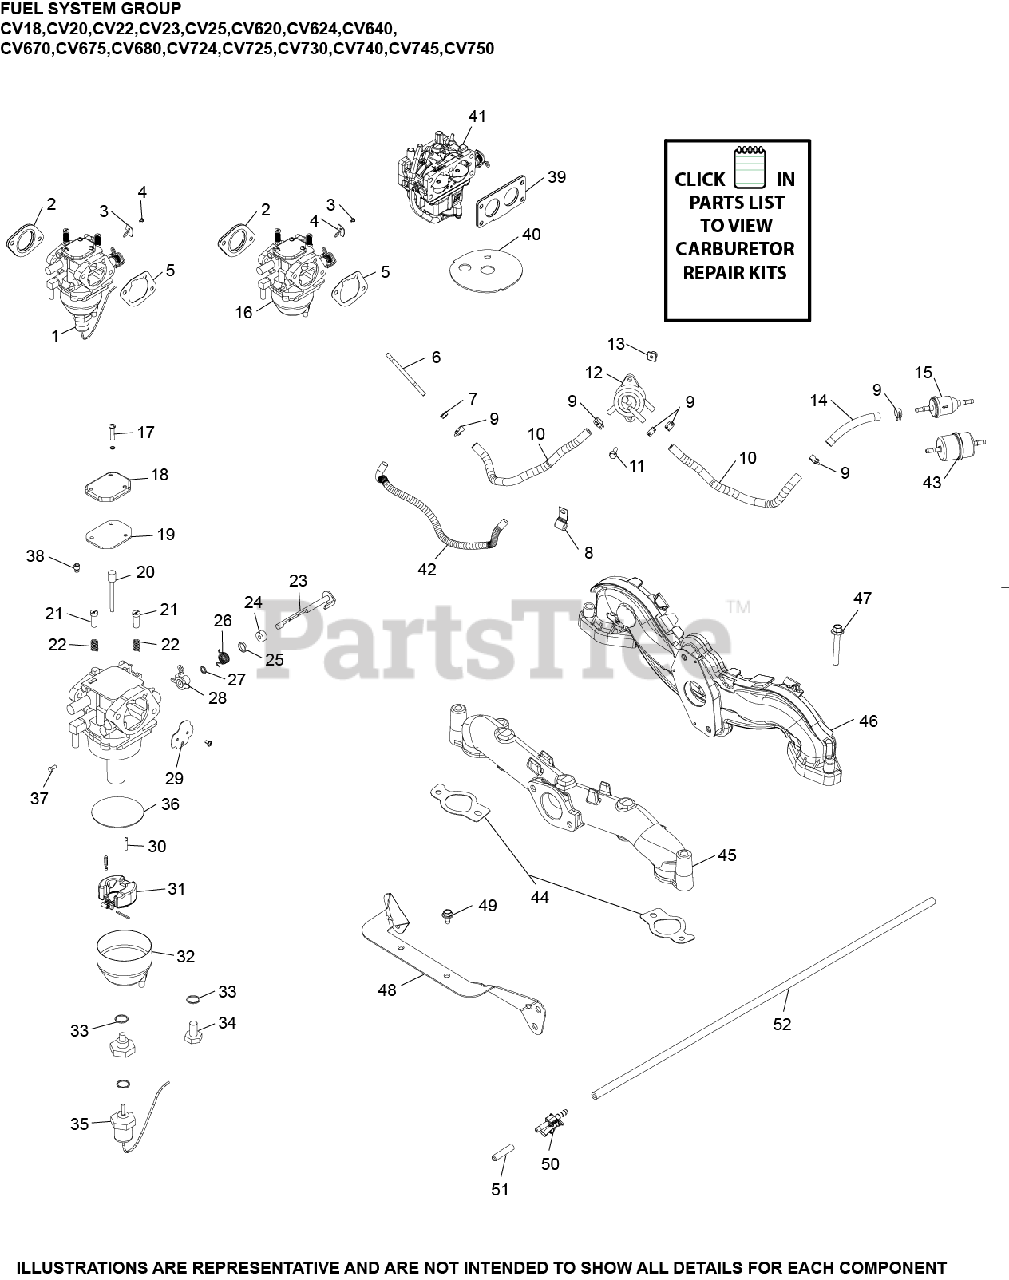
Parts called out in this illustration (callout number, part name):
2	GASKET, CARBURETOR
7	NUT, FLG M6X1.0
9	CLAMP, HOSE (KM)-USE 25 237 31-S
10	HOSE,LW PERM.FUEL 24.00"-USE 25 111 81-S
11	SCREW, TAP M6X1.7X18
12	PUMP, FUEL
13	NUT, PLASTIC - BLACK
42	SLEEVE,INSULATING 6.0"-USE 24 431 02-S
43	FILTER, FUEL
44	GASKET, INTAKE MANIFOLD USE 24 041 79-S
45	MANIFOLD, INTAKE
47	SCREW, FLG M6X1.0X55
2485392-S	KIT, CARBURETOR w/GASKETS
